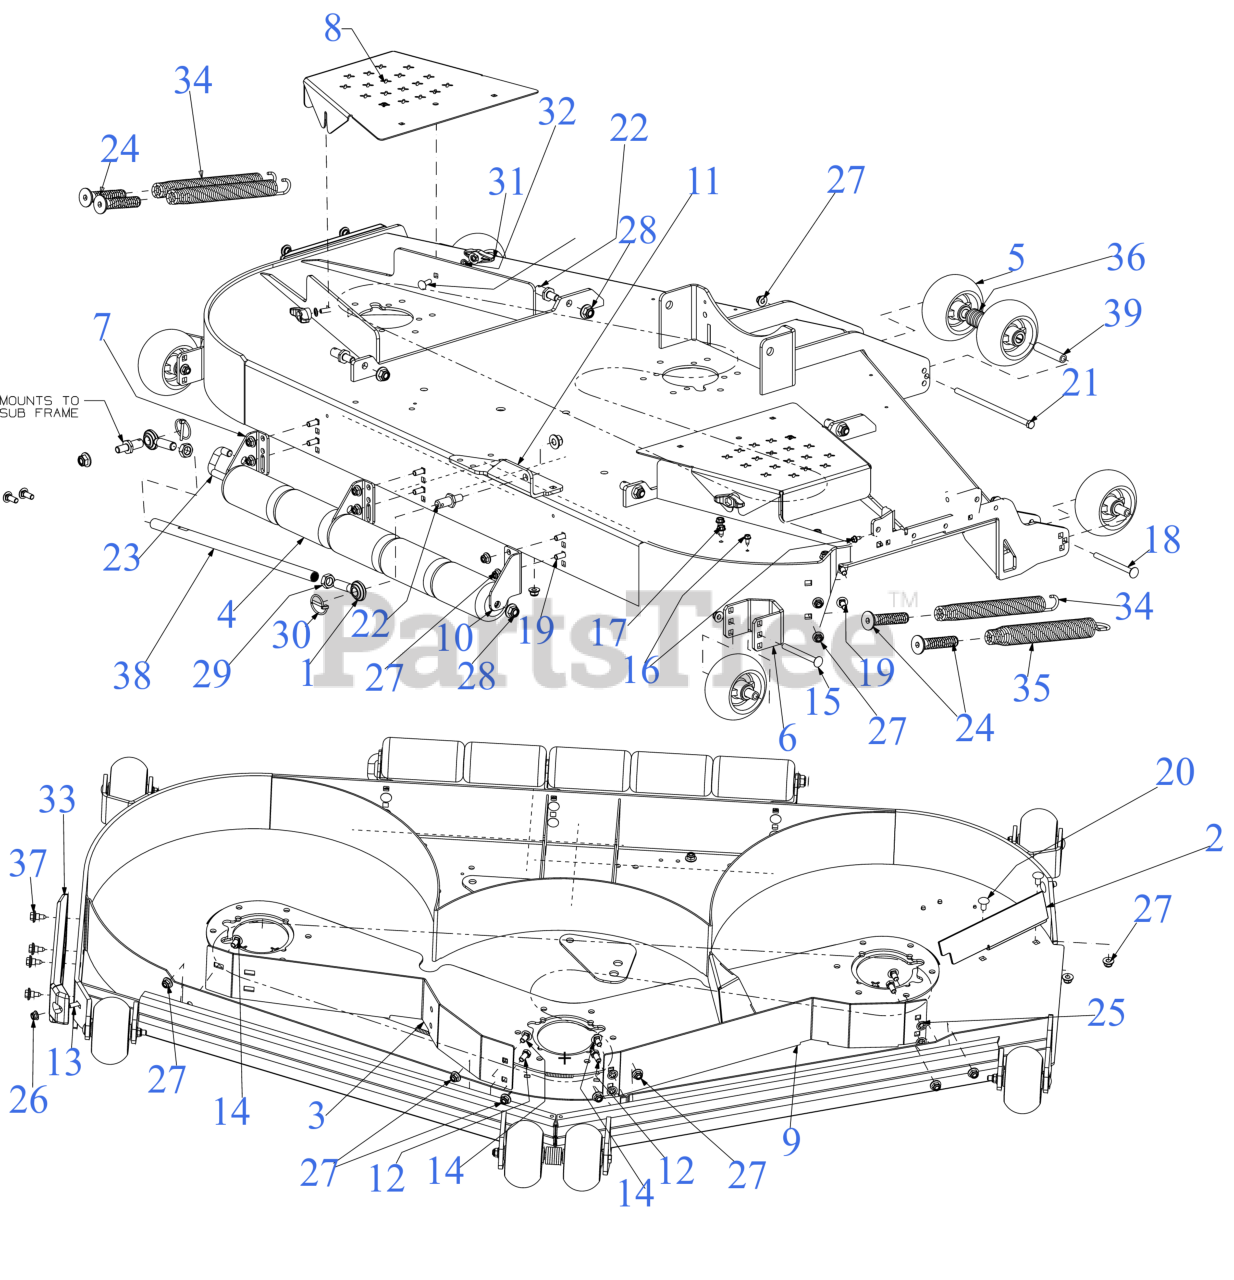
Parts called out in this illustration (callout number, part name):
1	MALE ROD END
2	BAFFLE - CHUTE
3	BAFFLE - 72" ADJ
4	ROLLER ASSEMBLY
4	FLANGE BEARING
5	5" DIA DECK WHEEL COMPLETE
5	FLANGE BEARING
6	72" FAB DECK SHELL
7	REAR MOUNT BRACKET
8	BELT COVER
10	REAR ROLLER BRACKET (RH)
11	DECK BELT GUIDE BRACKET
12	HEX SCREW 3/8-16 x .75
13	CARRIAGE BOLT 5/16-18 x 1.00
14	CARRIAGE BOLT 3/8-16 x .750 GR5
15	CARRIAGE BOLT 3/8-16 x 4.00 GR5
16	SCREW 1/4-20 X.500
17	SCREW 5/16-18 x .500
18	CARRIAGE BOLT 3/8-16 x 4.25 GR5
19	CARRIAGE BOLT 3/8-16 x 1.00 GR5
20	CARRIAGE BOLT 3/8-16 x .75
21	SCREW 3/8-16 x 8.5 GR5
23	REAR ROLLER PIN
24	SPRING INSERT SCREW
26	FLANGE LOCK NUT 5/16-18
29	HEX JAM NUT 5/8-18
30	LYNCH PIN .1875
31	WING KNOB 5/16-18
33	DECK SKID PLATE (LH)
34	EXTENTION SPRING 1.20 x 11.35
35	EXTENSION SPRING 1.44 OD x 11.36
36	FLAT WASHER
37	SHOULDER SCREW .43X.29X5/16-18 TT
38	TUBE .565 X .750 X 18.75"LG
39	WHEEL SPACER .38ID x 3.04LG
